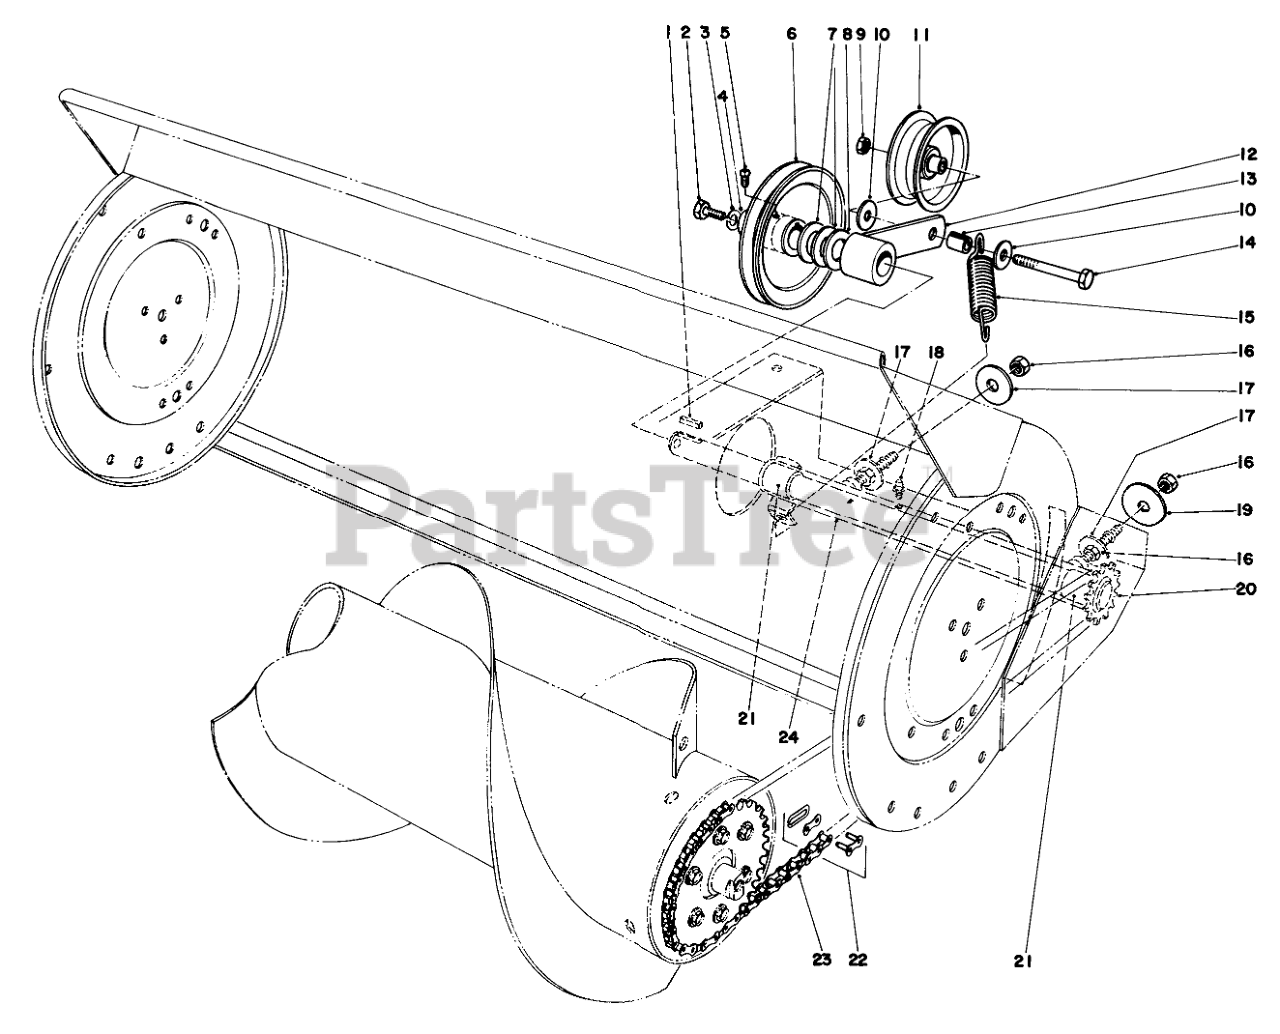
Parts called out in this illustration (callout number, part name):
1	KEY-SQUARE
2	SCREW-HH
3	WASHER-LOCK
4	WASHER-FLAT
5	SCREW-SQH
6	Pulley
7	Washer
8	Washer
9	NUT-LOCK, CONE
10	WASHER-FLAT
11	IDLER PULLEY ASM
12	Idler Arm
13	Spacer
14	SCREW-HH
15	Spring
16	NUT-HH
17	WASHER-FLAT
18	FITTING-GREASE
19	Flat Washer
20	SHAFT/SPROCKET ASM
21	Bushing-Jackshaft
22	LINK-CONNECTING
23	Roller Chain
24	Jackshaft Housing (Incl. Ref. #18)
